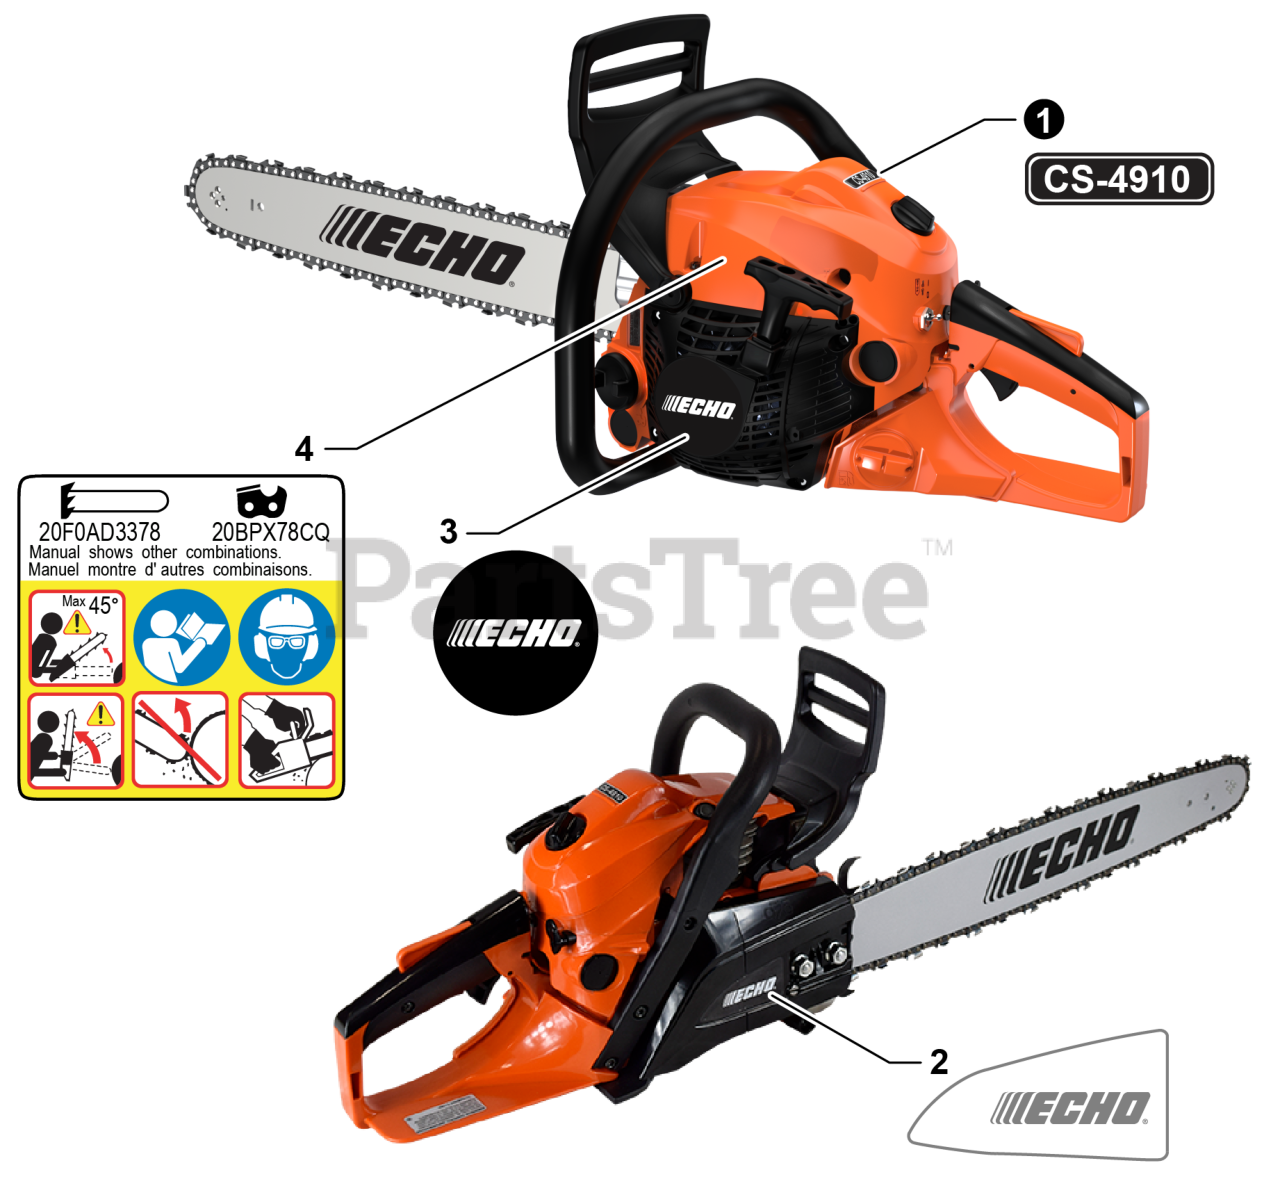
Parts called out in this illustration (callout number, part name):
1	LABEL - CS-4910
2	LABEL - ECHO
3	LABEL - RECOIL STARTER
4	LABEL - CAUTION
